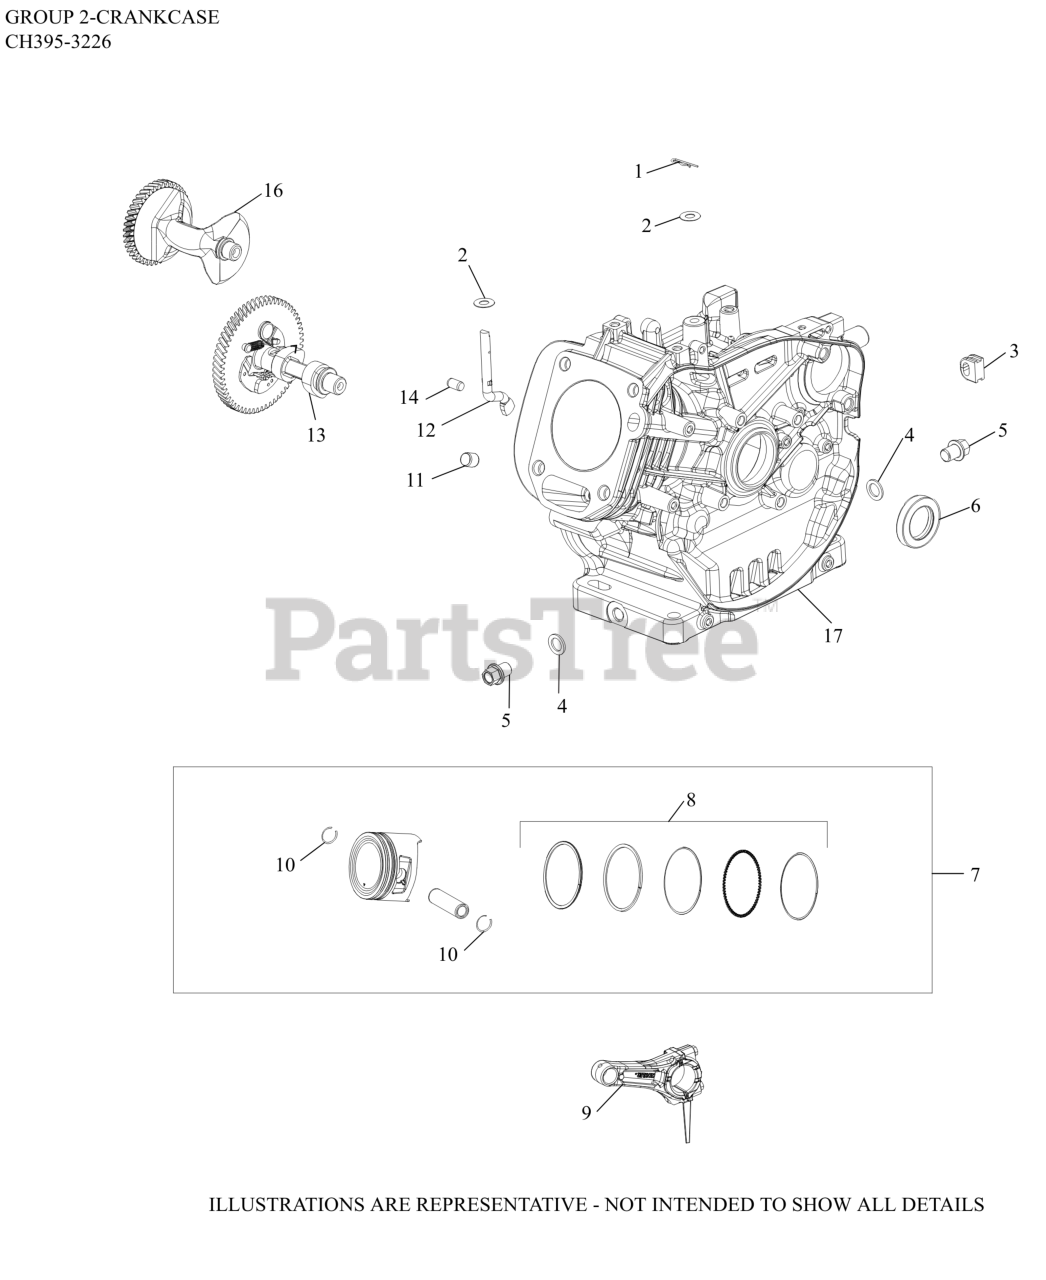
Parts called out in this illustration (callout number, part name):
1	CLIP, GOVERNOR SHAFT
2	WASHER, FLAT
3	GROMMET, CRANKCASE
4	WASHER, DRAIN PLUG
5	KIT, DRAIN PLUG
6	SEAL, RADIAL SHAFT
7	KIT, PISTON AND RINGS
8	RING SET- USE 17 874 06-S
8	RING, SET PISTION (std)
9	ROD, CONNECTING ASSEMBLY
10	RETAINER, PISTON PIN
11	PIN, DOWEL CYLINDER HEAD
12	SHAFT, GOVERNOR CROSS
13	CAMSHAFT ASSEMBLY
14	PIN, DOWEL
16	SHAFT, BALANCE
17	CRANKCASE
